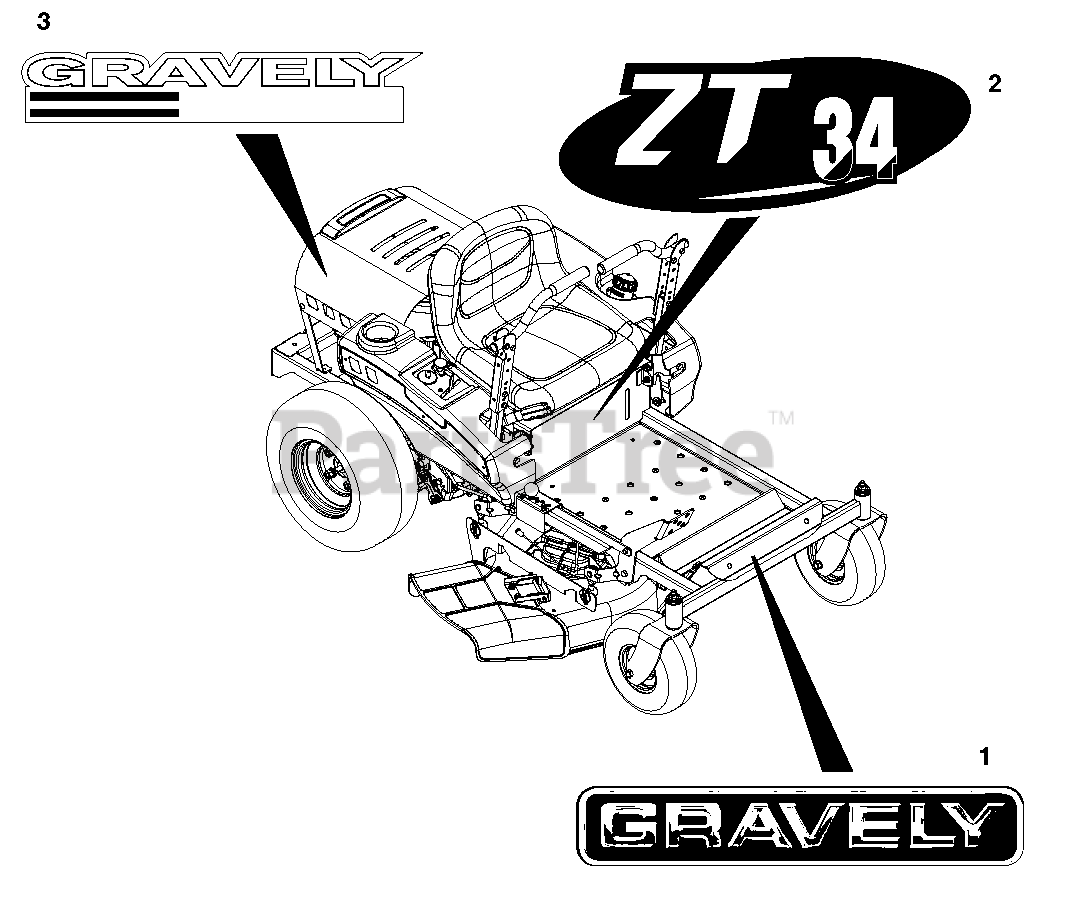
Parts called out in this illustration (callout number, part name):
1	Decal, Gravely Logo
2	Decal, 34 ZT
3	Decal, ZT Hood
